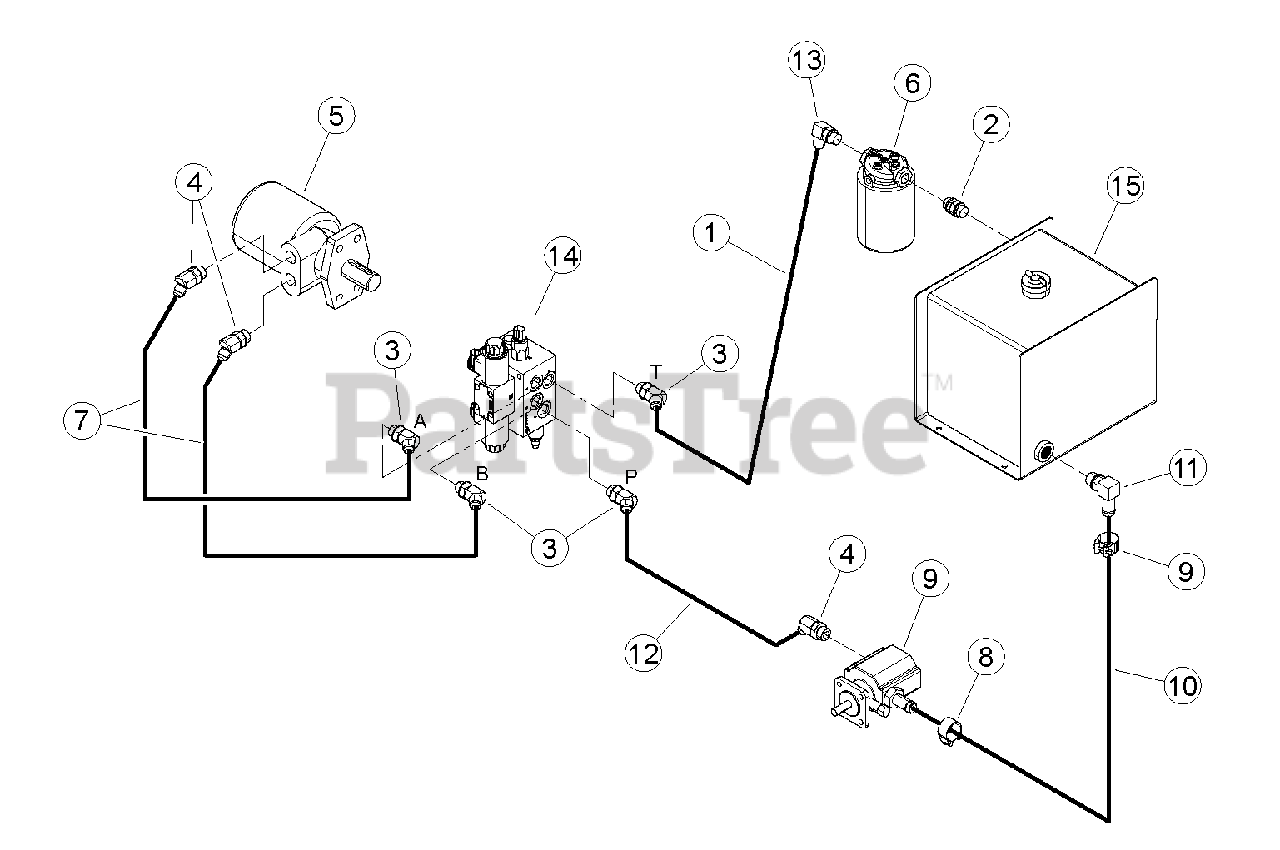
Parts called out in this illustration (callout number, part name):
1	HOSE ASSEMBLY, 72" -8FMJICSW / -8 FMJICSW
2	ADAPTER, -8 MORING / -8 MORING ADJ
3	ADAPTER, -8 MORB / -8 MJIC 45 DEG.
4	ADAPTER, -10 MORING / -8 MJIC 45 DEG.
5	MOTOR, 45 CU IN HYDRAULIC
6	ASSEMBLY, HYDRAUILC FILTER
7	HOSE, .375 X 36 -8 FMJIC / -8 FMJIC
8	CLAMP, 1-5/32 TO 7/32 OD RANGE T-BOLT
9	PUMP, 2 STAGE CW HI/LO 0.605 DISP.
10	HOSE, .75 ID X 24 IN. 100R4 HYD
11	ADAPTER, -10 MORING / .75 90 DEG. HOSE
12	HOSE, .50 X 48 -8 FMJIC / -8 FMJIC
13	ADAPTER, -8 MORING / -8 MJIC 90 DEG.
14	ASSEMBLY, HYDRAULIC FEED FLOW VALVE
15	WELDMENT, TANK HYDRAULIC 3.25 GAL
